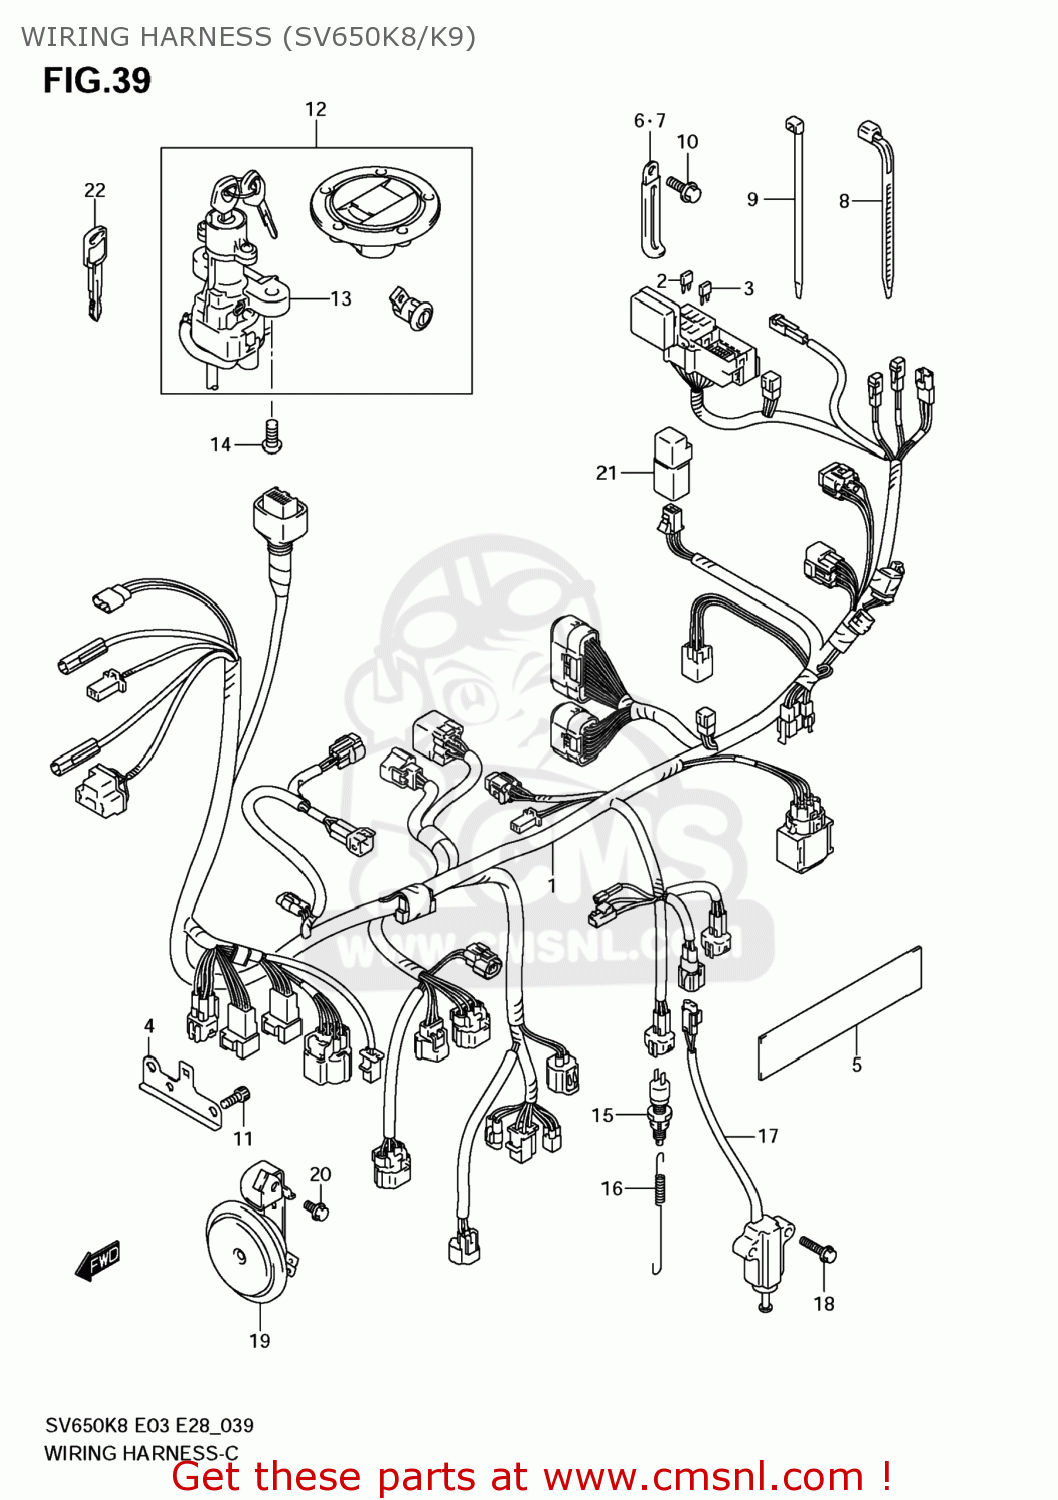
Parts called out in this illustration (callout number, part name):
1	HARNESS,WIRING
2	FUSE(10A)
3	FUSE(15A)
4	HOLDER,COUPLER
5	PROTECTOR(20X90)X1.0
6	CLAMP(L:45)
7	CLAMP(L:80)
8	CLAMP(L:95)
9	CLAMP(L:145)
10	BOLT
11	BOLT
12	LOCK SET
13	LOCK ASSY,STEERING
14	BOLT(8X20)
15	SWITCH ASSY,STOP LAMP
16	SPRING
17	SWITCH ASSY,SIDE STAND
18	BOLT
19	HORN ASSY
20	BOLT
21	RELAY ASSY
22	KEY,BLANK
